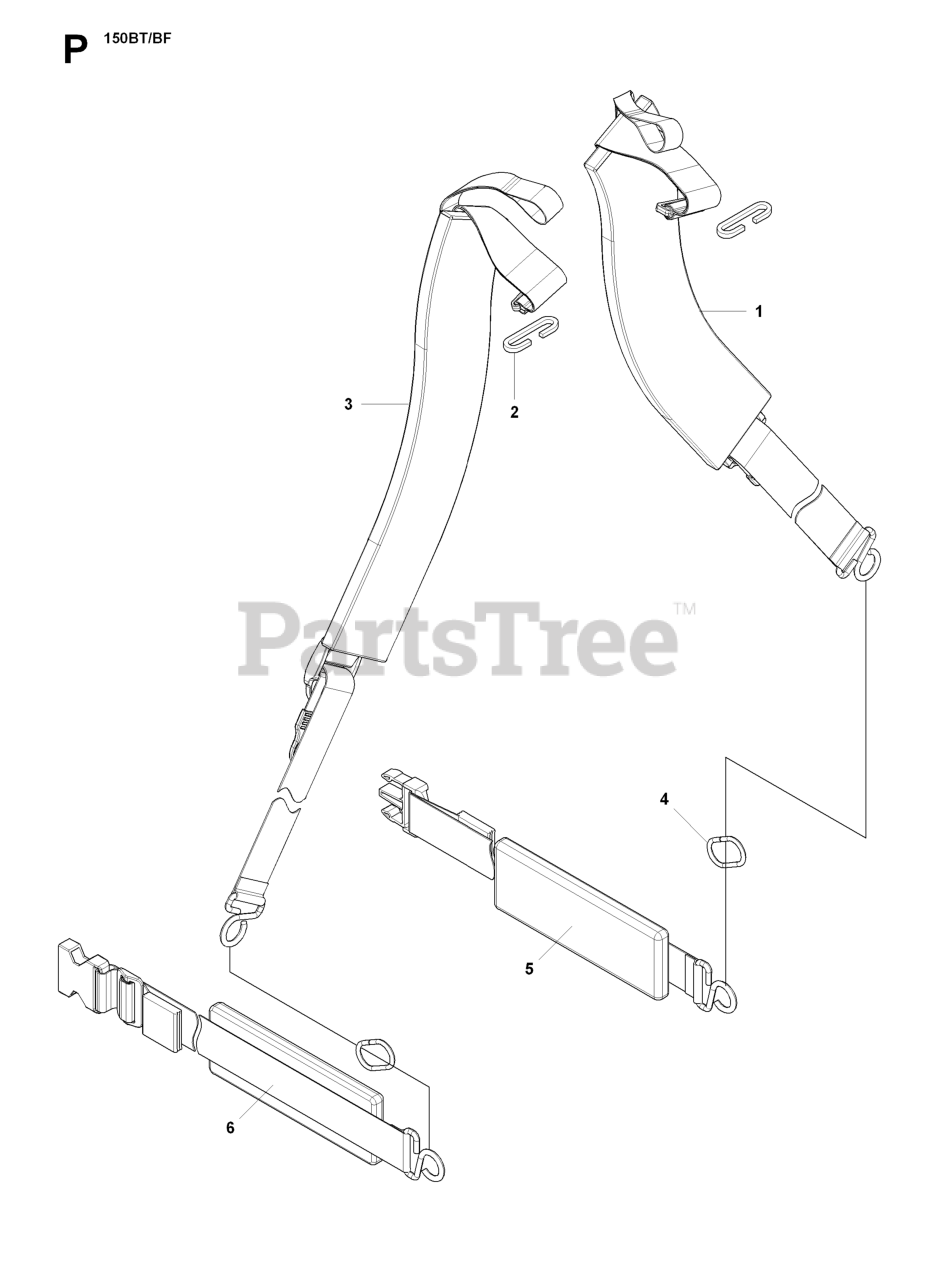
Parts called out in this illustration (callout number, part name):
1	TRANSMISSION ASSY
1	BAND ASSY(R)
2	GEARCASE LH W/BRG
3	GASKET TI
3	RP BAND ASSY (L)
4	NEEDLE BRNG LT
4	RING
5	THRUST WASHER
5	BAND B(R)
6	GEAR.PINION.INPUT
6	BAND B(L)
7	SHAFT.INPUT."D".TILLER
8	BEARING TI
9	WASHER, SEAL (2 2)
10	STEEL BALL KIT
11	SPRING-SHIFT CRT
13	BRACKET ASM.SHIFT.CRT
14	SHIFT FORK TI
16	SHAFT.SHIFTER.TILLER
20	GEAR ASSY CRT
21	GEAR-REV IDLR CRT
22	NEEDLE BEARING TI
24	LOCKWASHER
25	NUT.ASF.HEX.7/16
27	BEARING, SHAFT LH CRT
30	GROUND SHAFT ASS'Y
31	BEARING, SHAFT RH CRT
33	SPRCKT 8 GEAR CRT
34	SHAFT.SECONDARY.REDUCTION.CRT
35	SCRW WHIZ LOK CRT
36	SPROCKET.ASM.W/BEARING.TILLER
37	BEARING
38	SPROCKET, TINE
41	SHAFT.REDUCTION.TILLER
42	BRNG RACE T
44	SEAL ASM, OIL
48	GEARCASE RH W/BRG
49	TINE SHAFT
50	CHAIN.TILLER
51	SCREW
53	BEARING KIT
